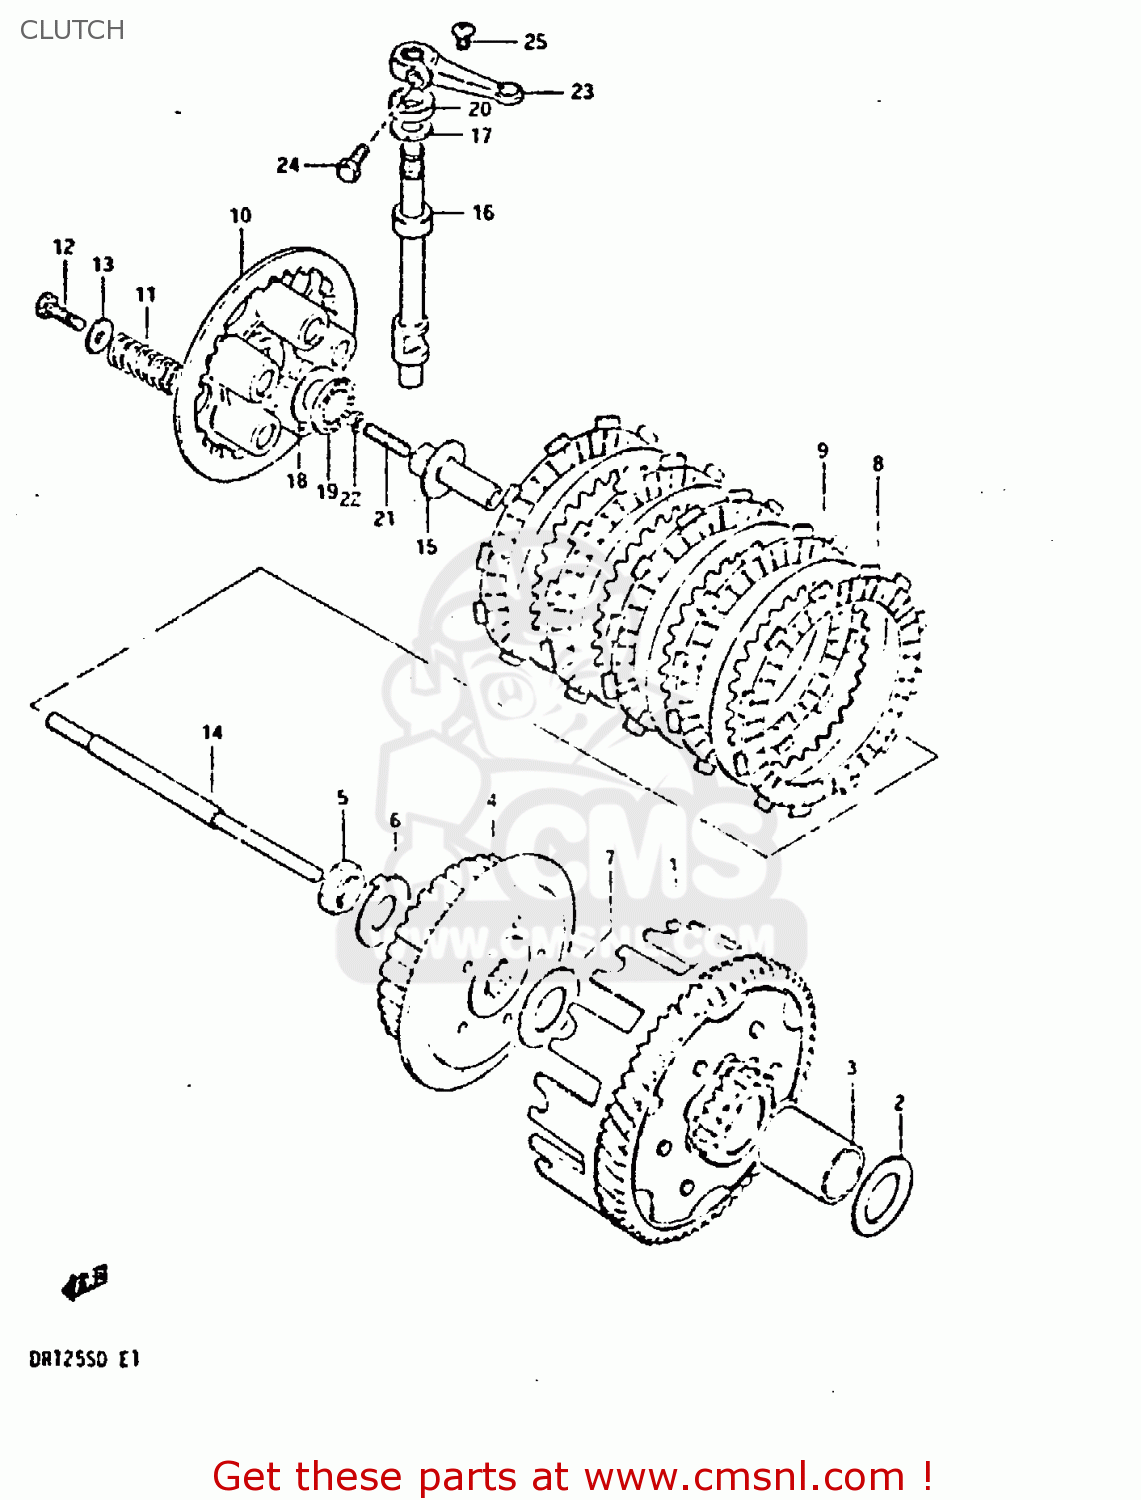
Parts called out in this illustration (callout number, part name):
1	GEAR ASSEMBLY,PRIMARY DRIVE
2	WASHER
3	SPACER
4	HUB,CLUTCH SLEEVE
5	NUT
6	WASHER
7	WASHER
8	PLATE,CLUTCH DRIVE
9	PLATE,CLUTCH DRIVEN (NAS)
10	PLATE,CLUTCH PRESSURE
11	SPRING
12	BOLT(5X16)
13	WASHER (5.5X16X1.2)
14	ROD,CLUTCH PUSH
15	PIECE,CLUTCH PUSH
16	CAMSHAFT,CLUTCH RELEASE
17	WASHER,THRUST
18	WASHER
19	BEARING(15X28X2)
20	OIL SEAL
21	SCREW
22	NUT 6MM
23	ARM,CLUTCH RELEASE
24	BOLT, UPPER
25	SCREW
